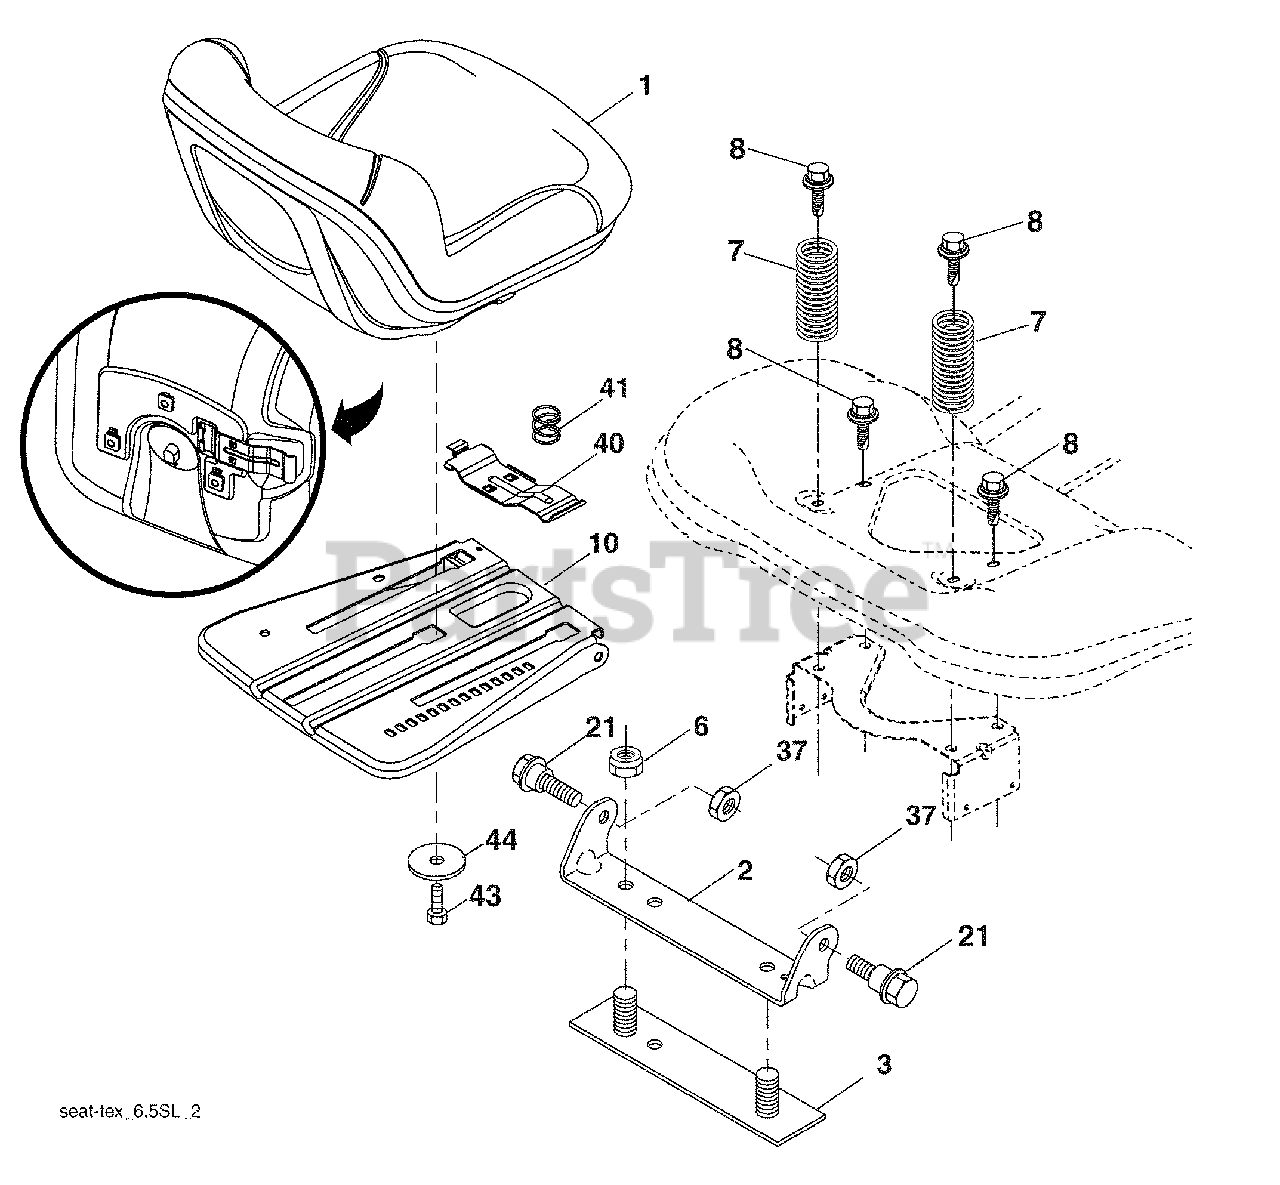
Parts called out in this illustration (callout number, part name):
1	Seat
2	Bracket Pivot Fender
3	Strap, Asm Fender
6	Nut, Lock w/Ins. 3/8-16 unc
7	Spring, Seat Cprsn
8	Bolt 5/16-18 unc x 3/4 w/Sems
10	Pan, Seat
21	Bolt, Shoulder 5/16-18
37	Nut, Lock 5/16-18 unc
40	Handle Slide Seat
41	Spring Latch Seat
43	Bolt 3/8-16 x 3/4
44	Washer 13/32 x 2-3/8 x 12 Ga.
